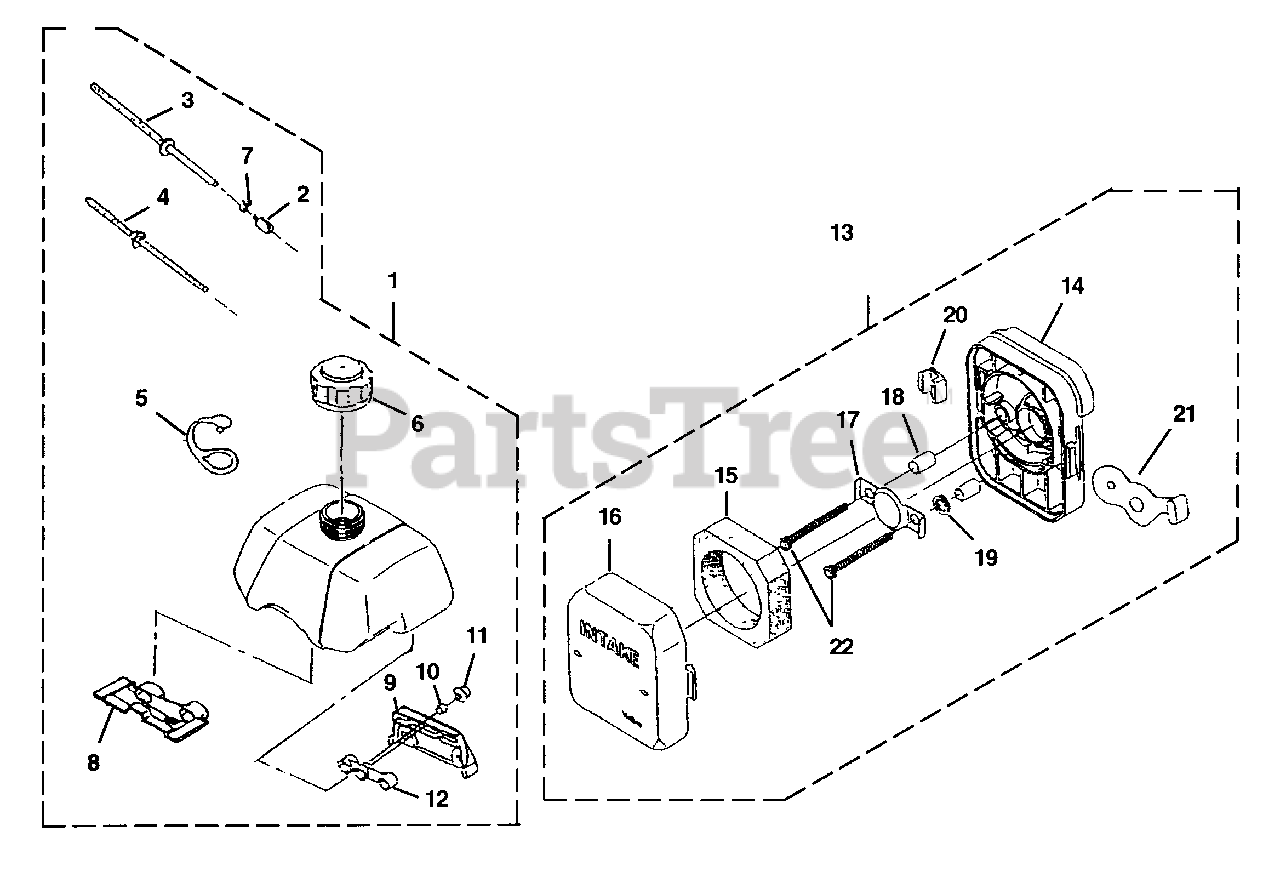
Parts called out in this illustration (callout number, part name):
1	FUEL TANK ASSEMBLY
2	FILTER-Fuel
5	CAP- Retainer
6	CAP - Fuel
7	HOSE CLAMP
8	BUMPER, Fuel Tank
9	BRACKET - Fuel Tank
11	BOLT (M5 X 14W)
12	BUMPER-Fuel Tank
13	AIR FILTER ASSEMBLY
14	BODY-Air Filter
15	FILTER-Air
16	COVER-Air Filter
17	PLATE-Air Filter
20	CLIP-Filter Cover
21	VALVE, CHOKE
22	SCREW-Socket Hd (M5 X 50)
